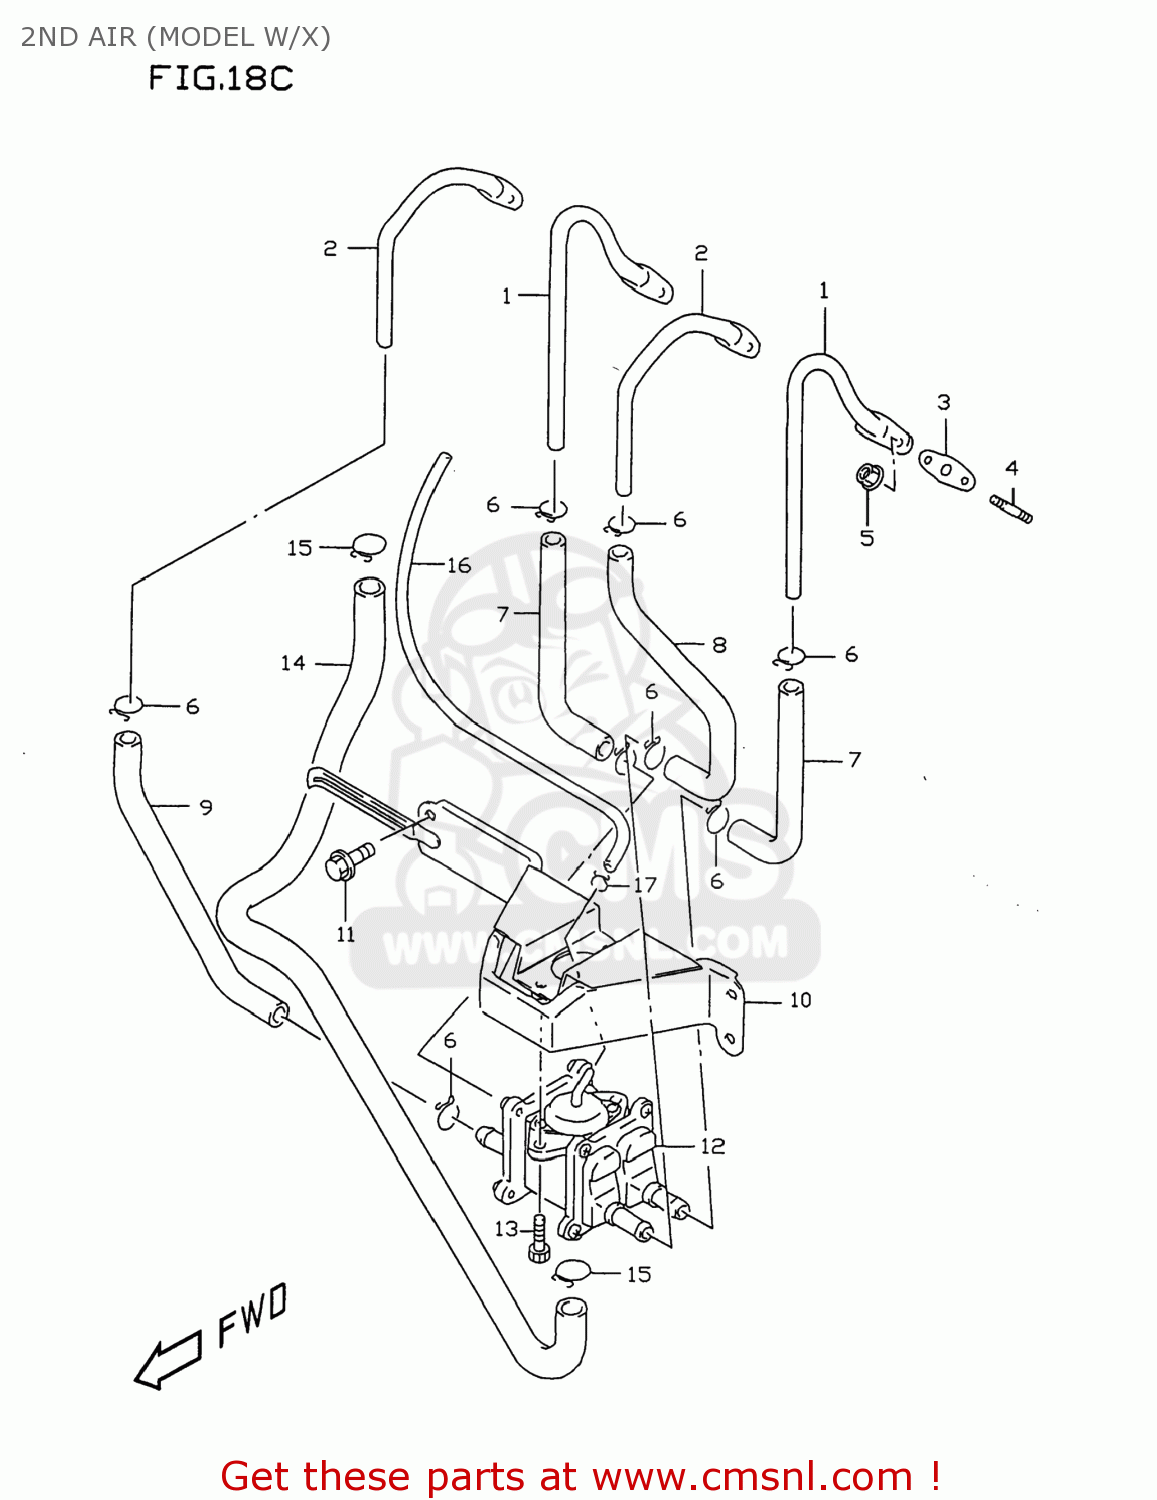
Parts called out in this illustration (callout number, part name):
1	PIPE COMP,SECOND AIR NO.1
2	PIPE COMP,SECOND AIR NO.2
3	GASKET,SECOND AIR PIPE (N (NAS)
4	STUD BOLT
5	NUT
6	CLIP
7	HOSE,2ND AIR VALVE NO.1
8	HOSE,2ND AIR VALVE NO.2
9	HOSE,2ND AIR VALVE NO.4
10	BRACKET,SECOND AIR VALVE
11	BOLT 6X12
12	VALVE ASSEMBLY,SECOND AIR
13	BOLT,OIL FILLE
14	HOSE,2ND AIR CLEANER
15	CLIP
16	HOSE(4X7X2000)
17	CLIP
